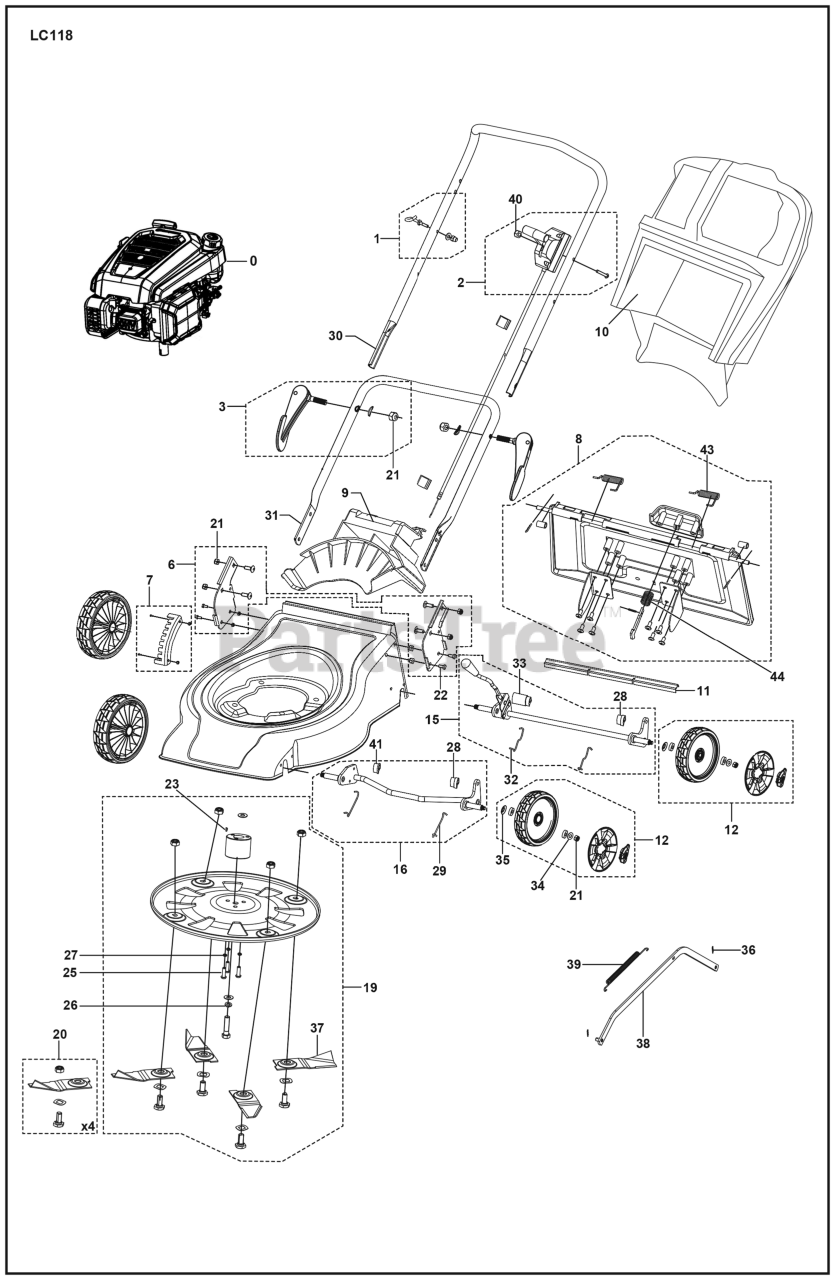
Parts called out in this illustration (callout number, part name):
21	LOCKNUT M8
22	BOLT - M8X16
26	Spring Washer
27	WASHER SPRING LOCK WASHER WITH
40	LOCKNUT M6
